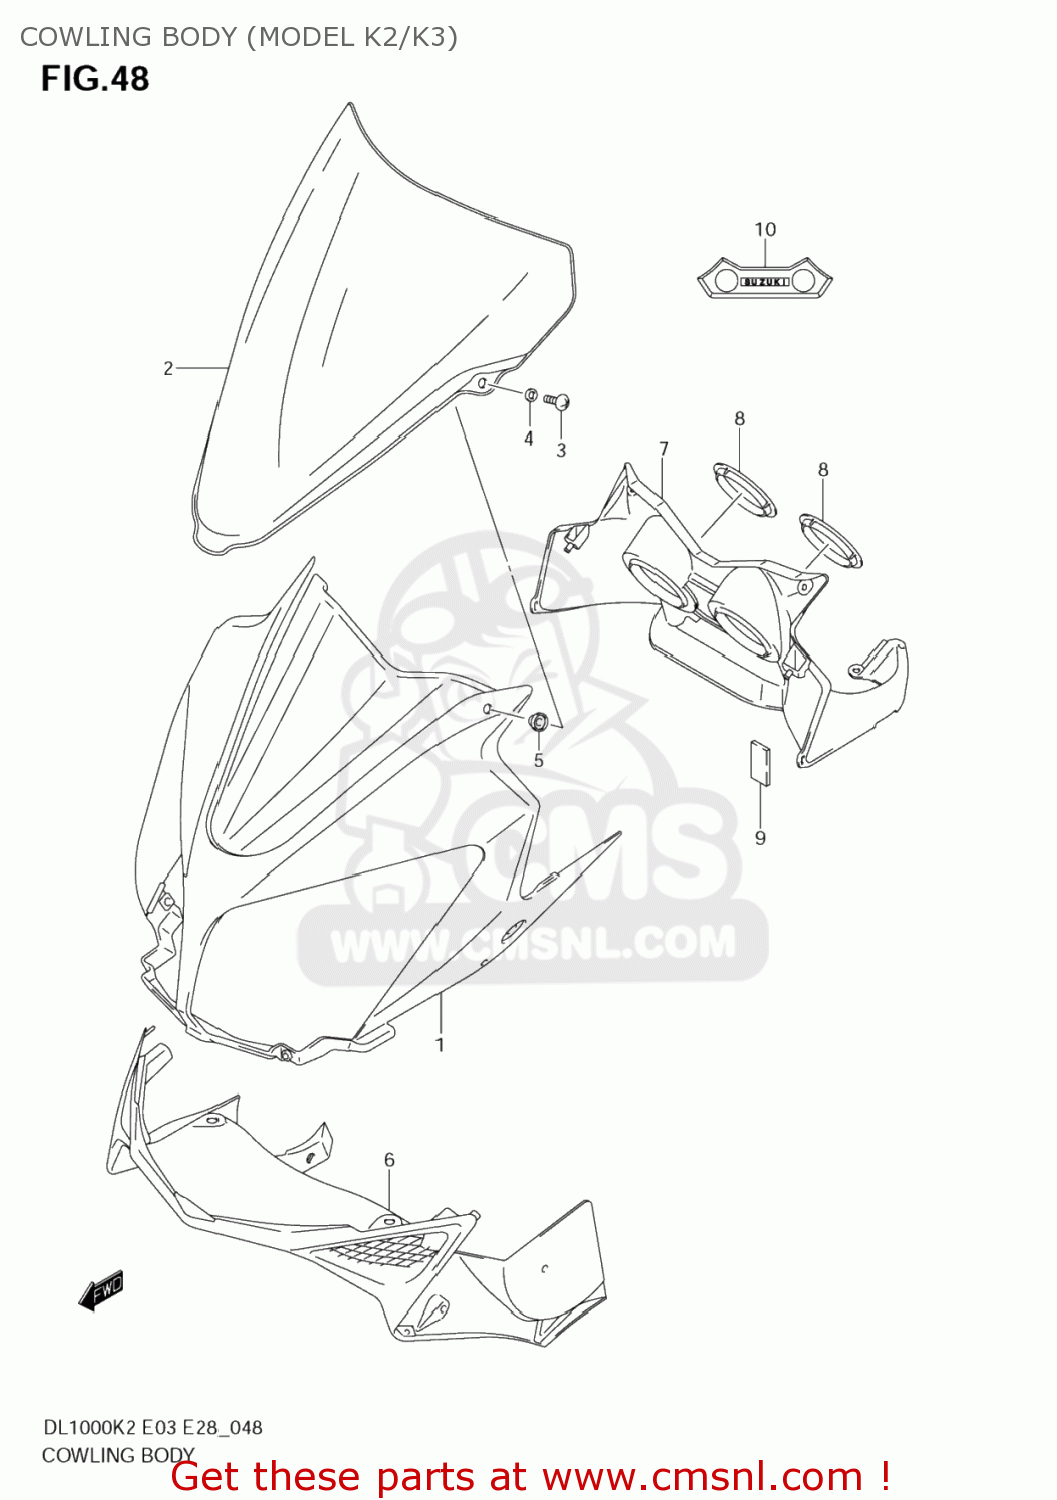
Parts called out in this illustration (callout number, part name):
1	COWLING,BODY(BLACK)
2	WINDSCREEN
3	SCREW(5X22)
4	WASHER
5	NUT,UNDER COWL BRACE RR
6	COVER,COWLING INNER
7	PANEL,METER
8	RING,METER PANEL
9	CUSHION
10	EMBLEM,PANEL M
